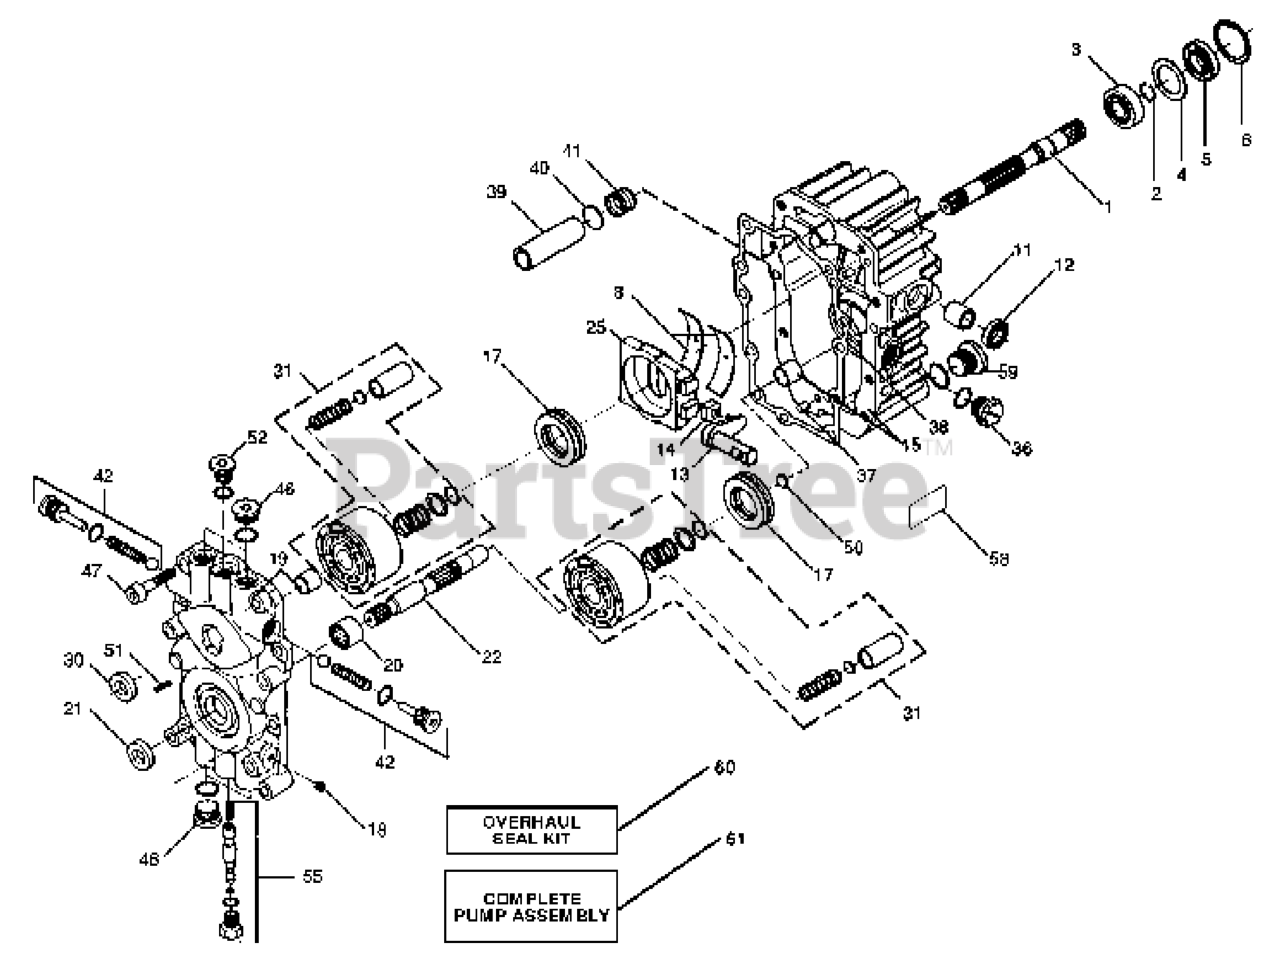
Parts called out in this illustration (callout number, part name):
1	SHAFT 2003022
2	RETAINIANG RING
3	BALL BEARING 2003043
4	SPACER
5	SEAL LIP
6	RETAINING PIN
8	CRADLE BEARING
12	SEAL LIP
13	TRUNION ARM
14	GUIDE 2000015 HYD
15	PUMP ASM COMP
17	BALL BEARING
19	KIT,CTR SECTION
20	NEEDLE BEARING
21	LIP SEAL 9008000-0127
25	SWASHPLATE,VARIAB
30	SEAL LIP
31	KIT,BLOCK CYLINDE
36	PLUG,PLASTIC
38	GASKET 2003060
39	FILTER 2003003
42	KIT,CHECK VALVE 2513014
55	KIT,BYPASS VALVE(2513011)
58	Adhesive Label, Bar Coded
60	KIT,OVERHEAD SEAL -2513013
61	PUMP ASM COMP
